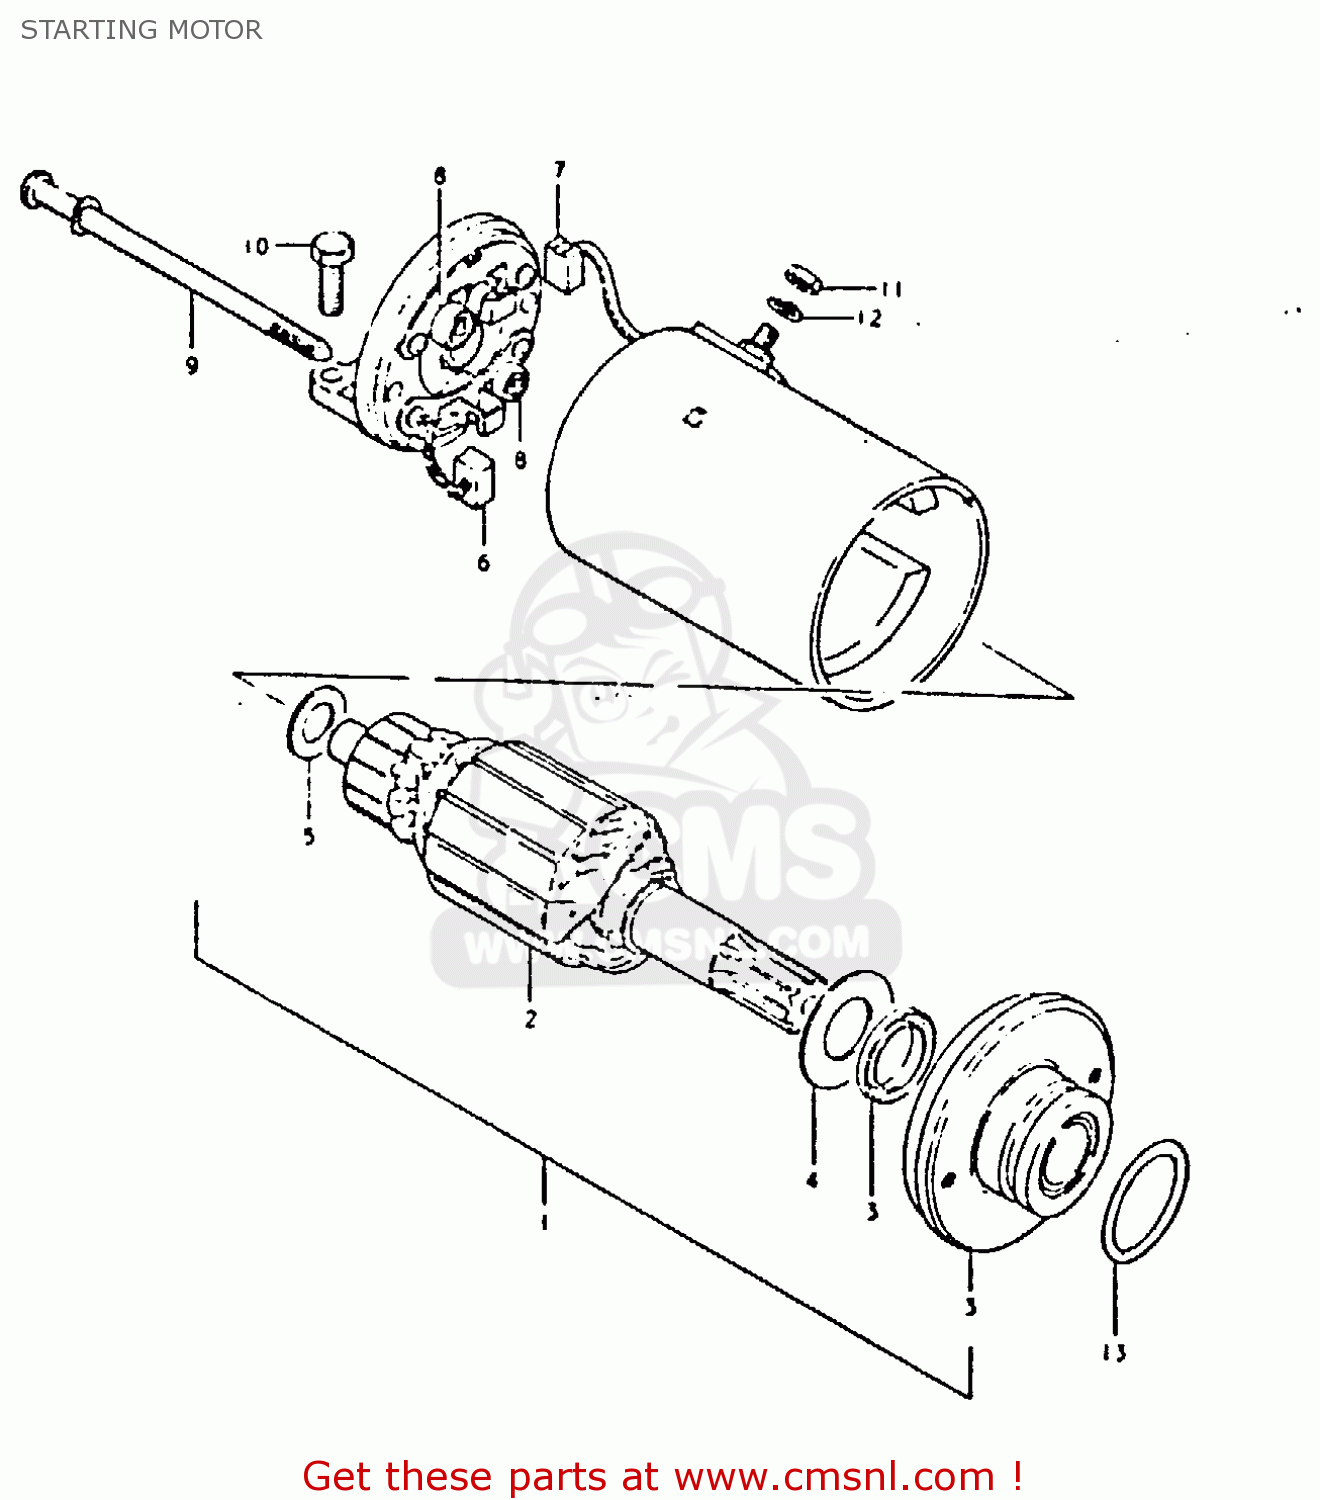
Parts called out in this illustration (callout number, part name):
1	MOTOR ASSEMBLY,STARTING
2	ARMATURE
3	SEAL,OIL
4	RING,SNAP
5	SHIM,ARMATURE
6	BRUSH(-)
7	BRUSH TERMINAL SET
8	SPRING
9	BOLT,STARTING MOTOR HOUSING
10	BOLT, UPPER
11	NUT 6MM
12	LOCK WASHER
13	O RING(D:2,ID:24.5)
